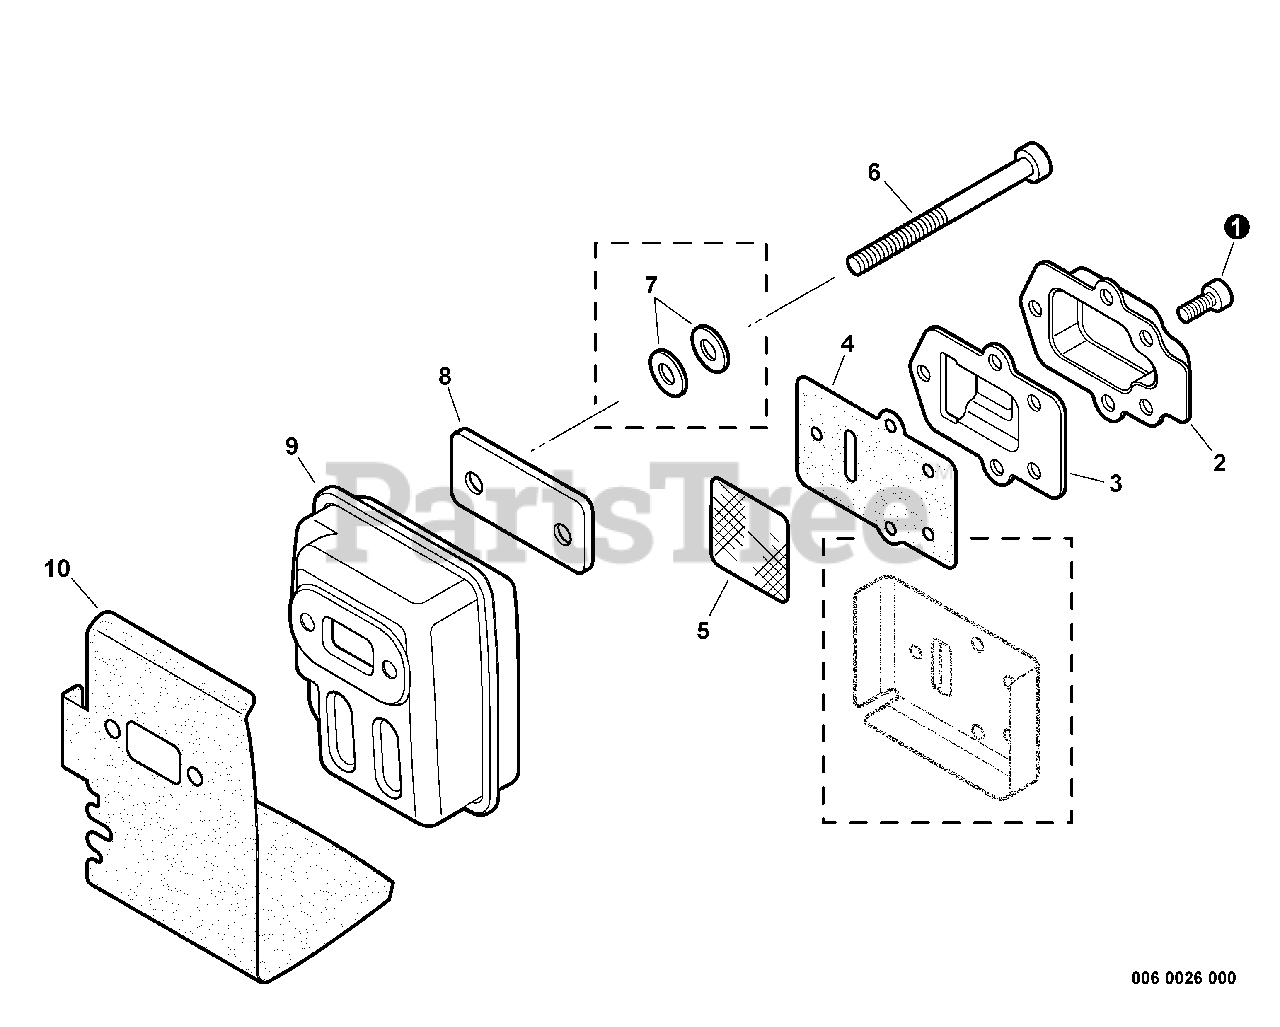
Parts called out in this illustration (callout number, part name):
1	SCREW - 4X10
2	GUIDE, EXHAUST - OUTER
3	GUIDE, EXHAUST - INNER
4	GASKET, EXHAUST
5	SCREEN, SPARK ARRESTOR
6	SCREW - 5X55
7	WASHER - CONICAL
9	MUFFLER
10	SHIELD, EXHAUST
